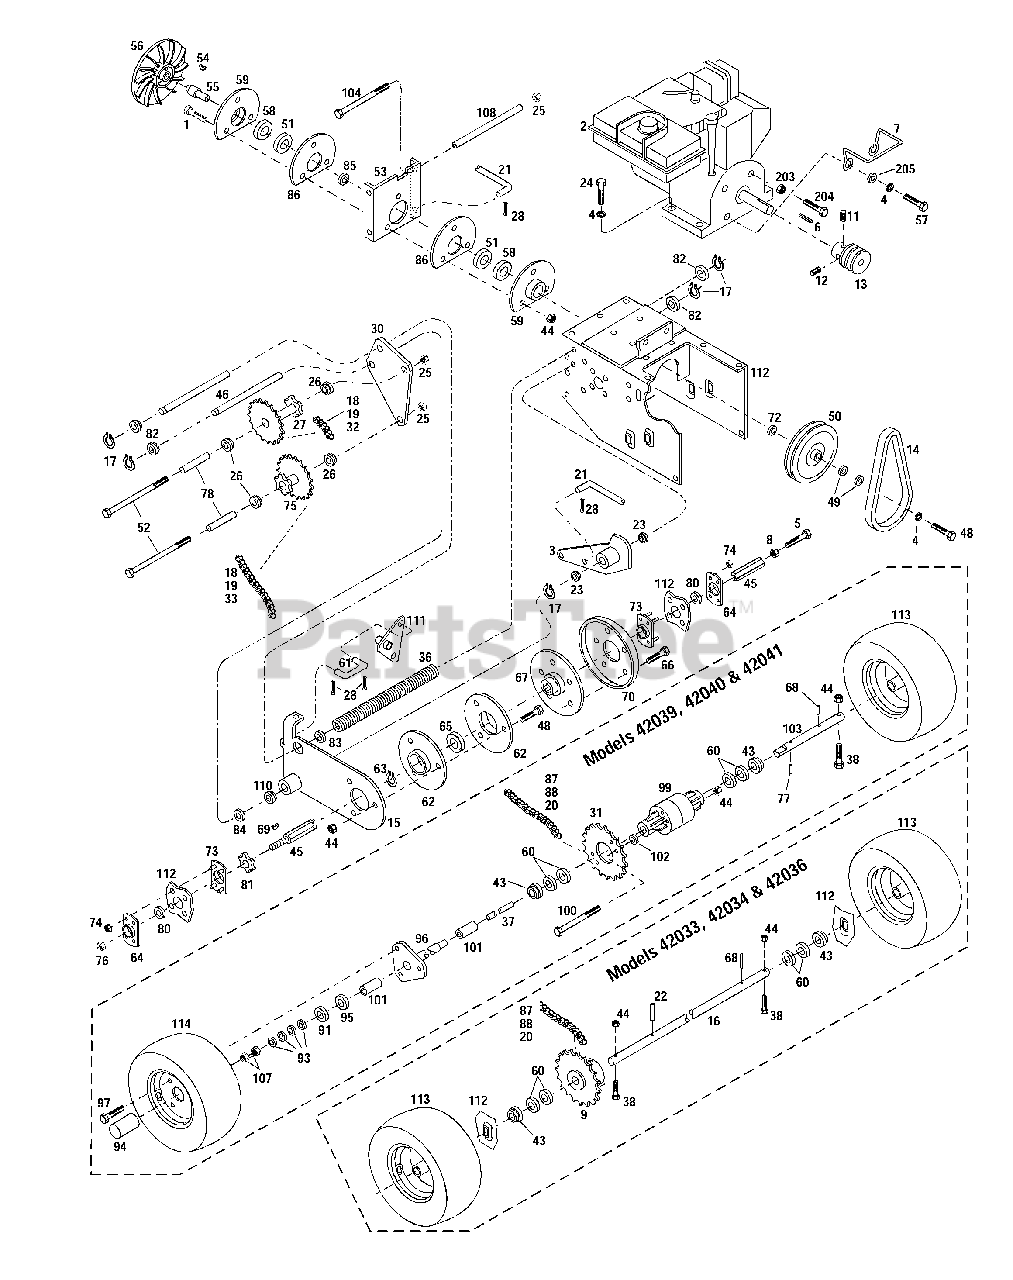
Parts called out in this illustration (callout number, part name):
1	Hex Bolt, 5/16-18 x 1
2	Tecumseh Engine, HMSK 80, 8 HP
3	Control Arm
4	Lock Washer, 5/16
5	Shoulder Bolt, 3/8-16 x 1-1/2
6	Square Key, 1/4 x 2-1/4
7	Belt Guide
8	Hex Jam Nut, 3/8-16 UNC
9	Sprocket Assembly
11	Set Screw, 5/16-18 x 1/2
12	Set Screw, 5/16-18 x 5/8
13	Engine Sheave
14	V-Belt
15	Drive Support
16	Axle Shaft
17	Retaining Ring
18	Offset Link (Half Link)
19	Connecting Link, #41
20	Final Drive Chain #40
21	Control Link
22	Drive Pin, 1/4 x 1-1/4, Type A
23	Flange Bushing
24	Hex Head Bolt, 5/16-18 x 1-1/2
25	Flange Lock Nut, 3/8-16
26	Flange Bearing
27	Sprocket Assembly, 9T/17T
28	Cotter Pin, 3/32 x 3/4
30	Support Plate
32	Drive Chain
33	Drive Chain
36	Compression Spring
37	Axle Shaft
38	Hex Head Bolt, 5/16-18 x 1-3/4
43	Flange Bushing, 7/8
44	Lock Nut, 5/16-18
45	Hex Shaft
46	Shaft Support
48	Cap Screw, 5/16-18 x 3/4
49	Special Flat Washer
50	Wheel Drive Sheave
51	Ball Bearing
52	Capscrew, 3/8-16 x 3-1/2
53	Drive Disc Support
54	Woodruff Key, 3/16 x 5/8
55	Spindle
56	Drive Plate
57	Hex Head Bolt, 5/16-24 x 1
59	Bearing Retainer
60	Flat Washer, 7/8
61	Connecting Link
62	Bearing Retainer
63	Snap Ring
64	Bearing Flange
65	Ball Bearing
66	Flange Bolt, 5/16-18 x 1/2
67	Friction Disc Hub
68	Drive Pin, 3/16 x 1-1/2
69	Woodruff Key
70	Molded Friction Disc
72	Special Washer
73	Bearing Flange Assembly
74	Lock Nut, #10-24
75	Sprocket Assembly, 9T/30T
76	Jam Nut, 1/2-13
77	Drive Pin
80	Ball Bearing
81	Sprocket, 9T
82	Nylon Bushing
83	Special Flat Washer
84	Flat Washer, 5/8
85	Spacer
86	Bearing Retainer
87	Connecting Link
88	Offset Link (Half Link)
91	D-Hole Drive Washer
93	Disc Spring
94	Dust Cap
95	Friction Disc
96	Flange & Axle Tube Assembly
97	Lug Bolt
99	Differential Assembly
101	Nylon Bushing
102	Spacer
103	Axle Shaft
104	Hex Head Bolt, 3/8-16 x 8-1/2
107	Jam Nut, 1/2-13
108	Tubular Spacer
110	Flange Bearing
111	Speed Control Arm
112	Frame
113	Wheel & Tire Assembly
114	Wheel & Tire Assembly
203	Hex Nut, 5/16-24
204	Screw, Hex Cap, 5/16-24 x 4-1/2
205	Flat Washer, 5/16
